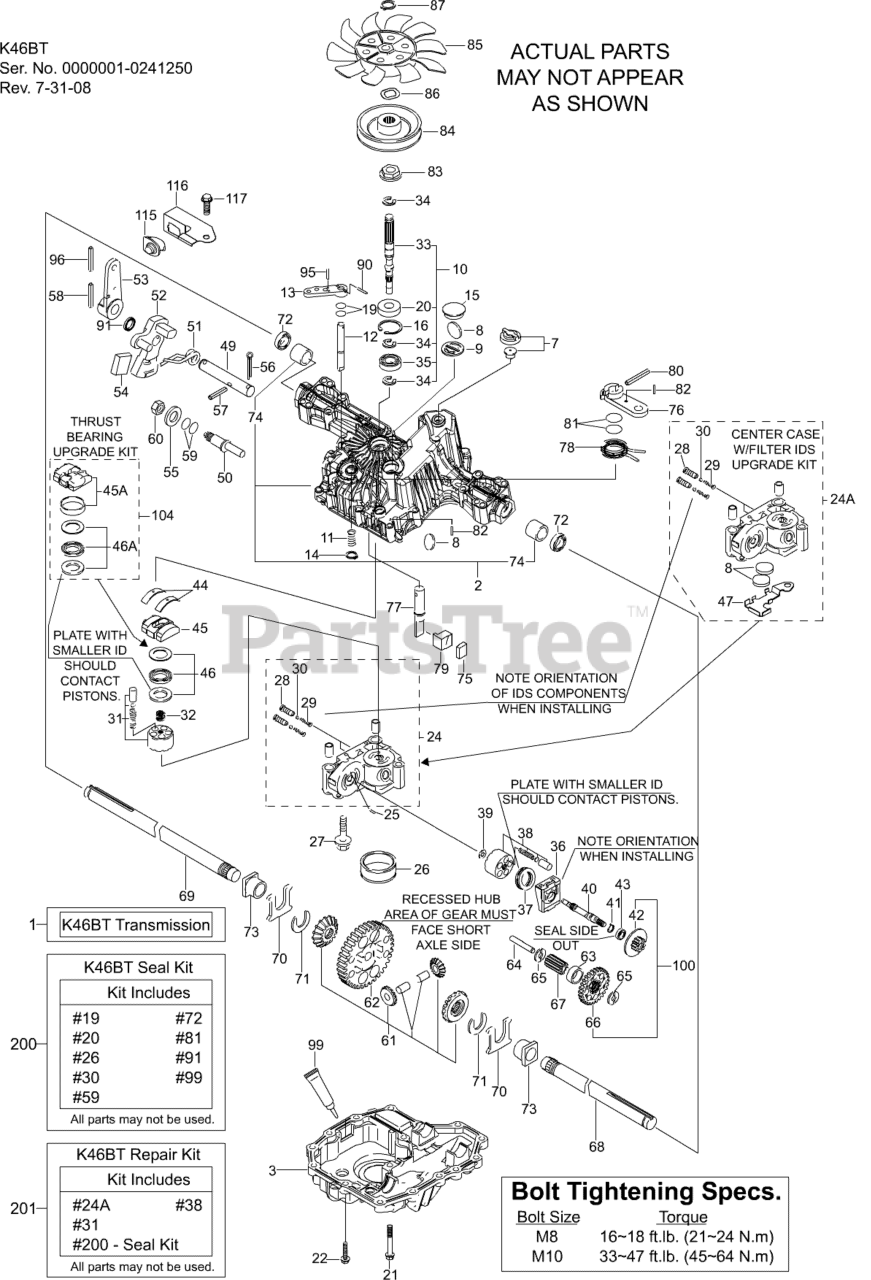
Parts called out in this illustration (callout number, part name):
9	MAGNET HOLDER
22	TAPPING SCREW
41	SNAP RING S15
72	RP SEAL.19, 19216334280
78	RETURN SPRING
85	FAN.BLACK.1A646083070
87	RETAINING RING **
